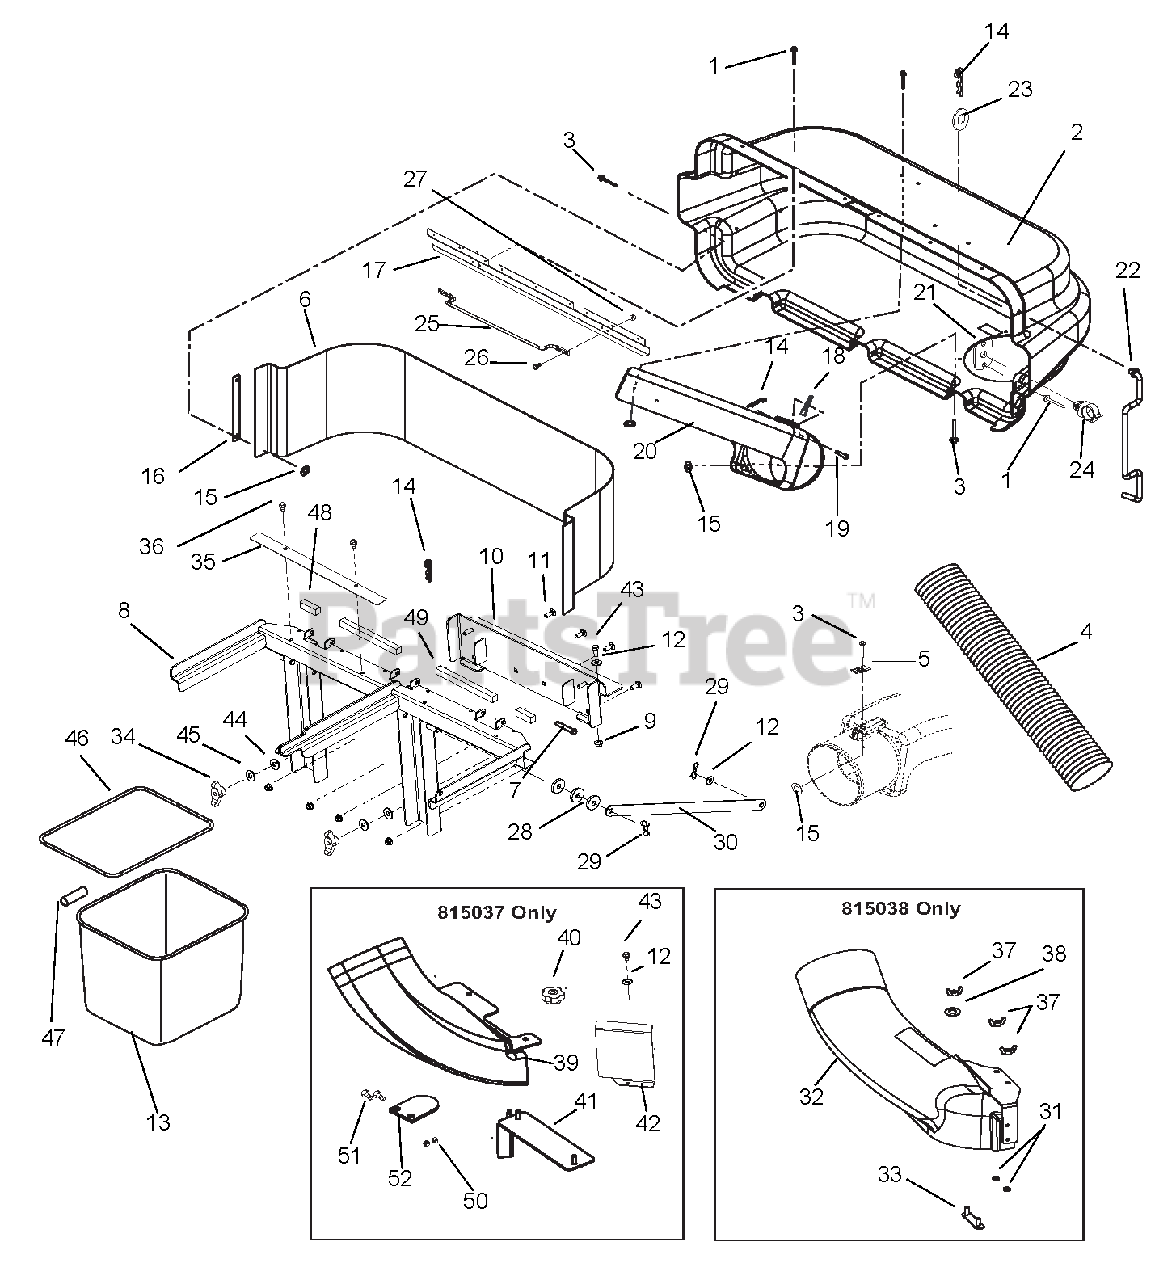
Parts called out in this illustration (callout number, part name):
1	RVT-POP .187X.402 DOME ST
2	BAGGER COVER W/DECAL
3	RVT-POP .187X.375
4	HOSE, FLEXIBLE-47"
5	THUMB LATCH
6	SCREEN, BAGGER
7	PIN-CLEV .371X3.25 YWZC
8	WMT, BAGGER FRAME
9	@NUT-LK-NYL-FLG .38-16 YWZC
10	WMT, MOUNTING PLATE
11	@BLT-RDHDSQNK .38-16X1.00 G5YZ
12	@WSHR-FL-STL.438X1.00X.083 YWZ
13	BAG, MESH ZOOM
14	PIN-HAIR, ENDRIES #25 YWZC
15	@WSHR-FL-STL.219X.50X.049 YWZC
16	STRAP,COVER
17	LATCH, BAGGER (MZ)
18	INDICATOR, FLOW
19	PIN-CLEV .309 X 1.625 YWZC
20	BOOT,UPPER
21	PLATE, ROD CLIP
22	PROP-ROD,BAGGER
23	@WSHR-FL-STL.406X.812X.065 YWZ
24	CLIP-.38
25	BAGGER HANDLE
26	@BLT-RDHDSQNK .25-20X.75 G5YZ
27	NUT-LUG .50-20 YWZC
28	WSHR-FL-STL .515X1.625X.250 YZ
29	PIN,BOW TIE LOCKING .091X1.875
30	WMT-STRAP, BAGGER
31	@NUT-LK-CTR-JAM .31-18 YWZC
32	ASM, BAGGER BOOT
33	WMT-BOOT MOUNT STRAP
34	NUT-WING .38-16
35	BRKT-BAGGER OVERLAP
36	@SCR-TAP .31-18X.50 HWH TR YWZ
37	NUT-NYLK WING .312-18 YWZC
38	@WSHR-FL-STL.406X.812X.065 YWZ
39	ASSY, 34" BAGGER BOOT
40	KNOB-CLAMPING, .312-18 NYLOC
41	WLDMNT, 34" BAGGER MOUNT
42	DEFLECTOR, MUFFLER
43	@BLT-HEX .38-16X1.00 GR5 YWZC
44	WSHR-FL-STL .390X1.5X.125 YWZC
45	@WSHR-LK .38X.094 REG YWZC
46	FRAME, ZOOM BAG
47	HOSE, .38 X.50 X 3.00 VINYL
48	BLOCK, 4 IN FOAM GRASS
49	FOAM, 9.00 X 1.00 X 1.25
50	NUT .25-20 SPEED
51	BLT-HEX .31-24X.75 GR8 YWZC
52	VANE, BLADE
